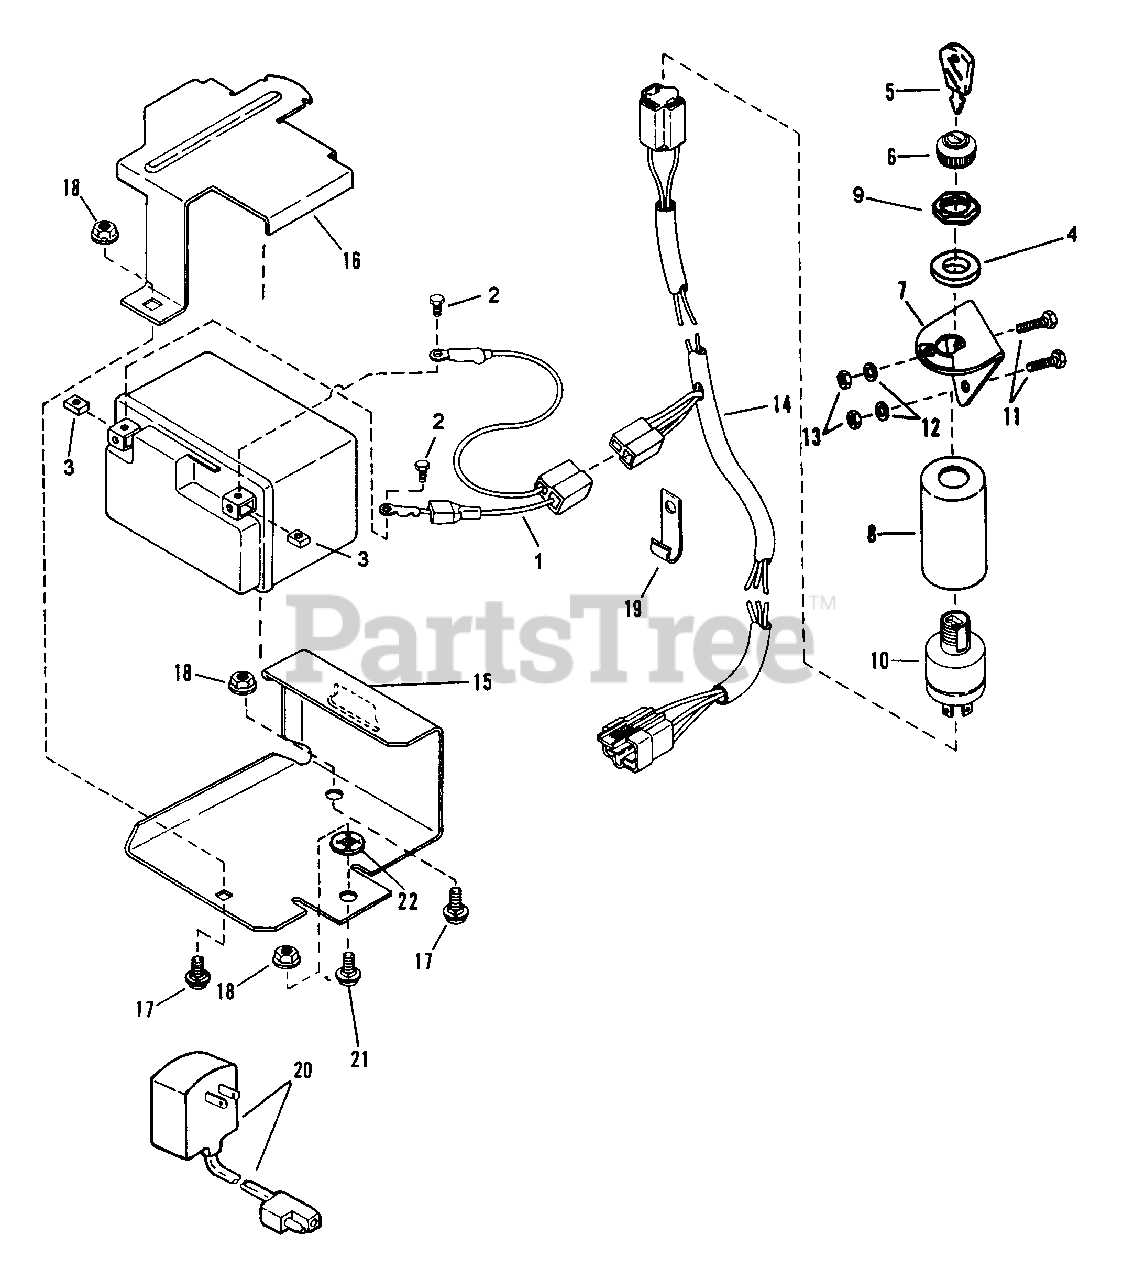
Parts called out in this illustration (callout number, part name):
1	HARNESS, Battery
2	SCREW, #10-24 x 1/2" Hex Head Cap
3	NUT, #1024 Square
4	SPACER
5	KEY, Switch (With Cover)
6	BEZEL
7	BRACKET, Ignition Switch
8	COVER, Switch
9	NUT, 3/4-20 Hex Lock
10	SWITCH, Ignition
11	SCREW, 1/4-28 x 1-3/8" Hex Head Cap, Gr. 5
12	WASHER, 1/4 Internal Tooth Lock
13	NUT, 1/4-28 Hex Grade 5 or B
14	HARNESS, Wiring
15	BRACKET, Battery
16	COVER, Battery
17	BOLT, 5/16-18 x 1/2" Short Nk. Carriage, Gr. 5
18	NUT, 5/16-18 Hex Flange Lock Grade 5
19	CLIP, Wiring
20	CHARGER, Battery (120 Volt - 60 Hertz) (wire plug drawing wrong)
21	BOLT, 5/16-18 x 5/8" Short Nk. Carriage, Gr. 5
22	RETAINER, 5/16 Bolt
